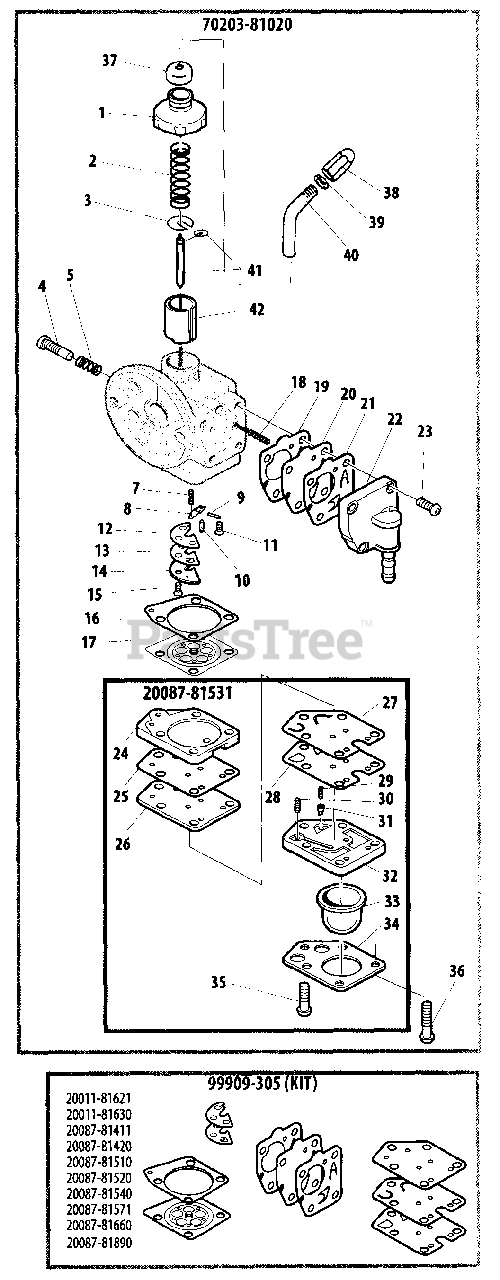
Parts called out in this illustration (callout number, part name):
1	CAP, CARBURETOR
2	SPRING
3	RETAINER
4	SCREW, IDLE ADJUST
5	SPRING
7	SPRING
8	LEVER, METERING
9	PIN, METERING LEVER
10	VALVE, INLET NEEDLE
11	SCREW, METERING LEVER PIN
12	GASKET
13	VALVE, CHECK
14	PLATE
15	SCREW, METERING LEVER PIN
16	GASKET, METERING
17	DIAPHRAGM, METERING
18	SPRING
19	GASKET, METERING
20	DIAPHRAGM, METERING
21	VALVE, PUMP
22	BODY, PUMP
23	SCREW
24	BASE, PURGE
25	GASKET
26	PLATE, PUMP
27	DIAPHRAGM
28	GASKET
29	SPRING, RETURN
30	SPRING
31	VALVE
32	COVER, PUMP
33	BULB, PURGE
34	PLATE
35	SCREW
36	SCREW
37	GROMMET
38	NUT, CABLE ADJUST
39	LOCKNUT
40	GUIDE, CABLE
41	NEEDLE, JET
42	VALVE, THROTTLE
20087-81531	PRIMER PUMP ASSY
70203-81020	CARBURETOR
99909-305	DIAPHRAGM/GASKET KIT
